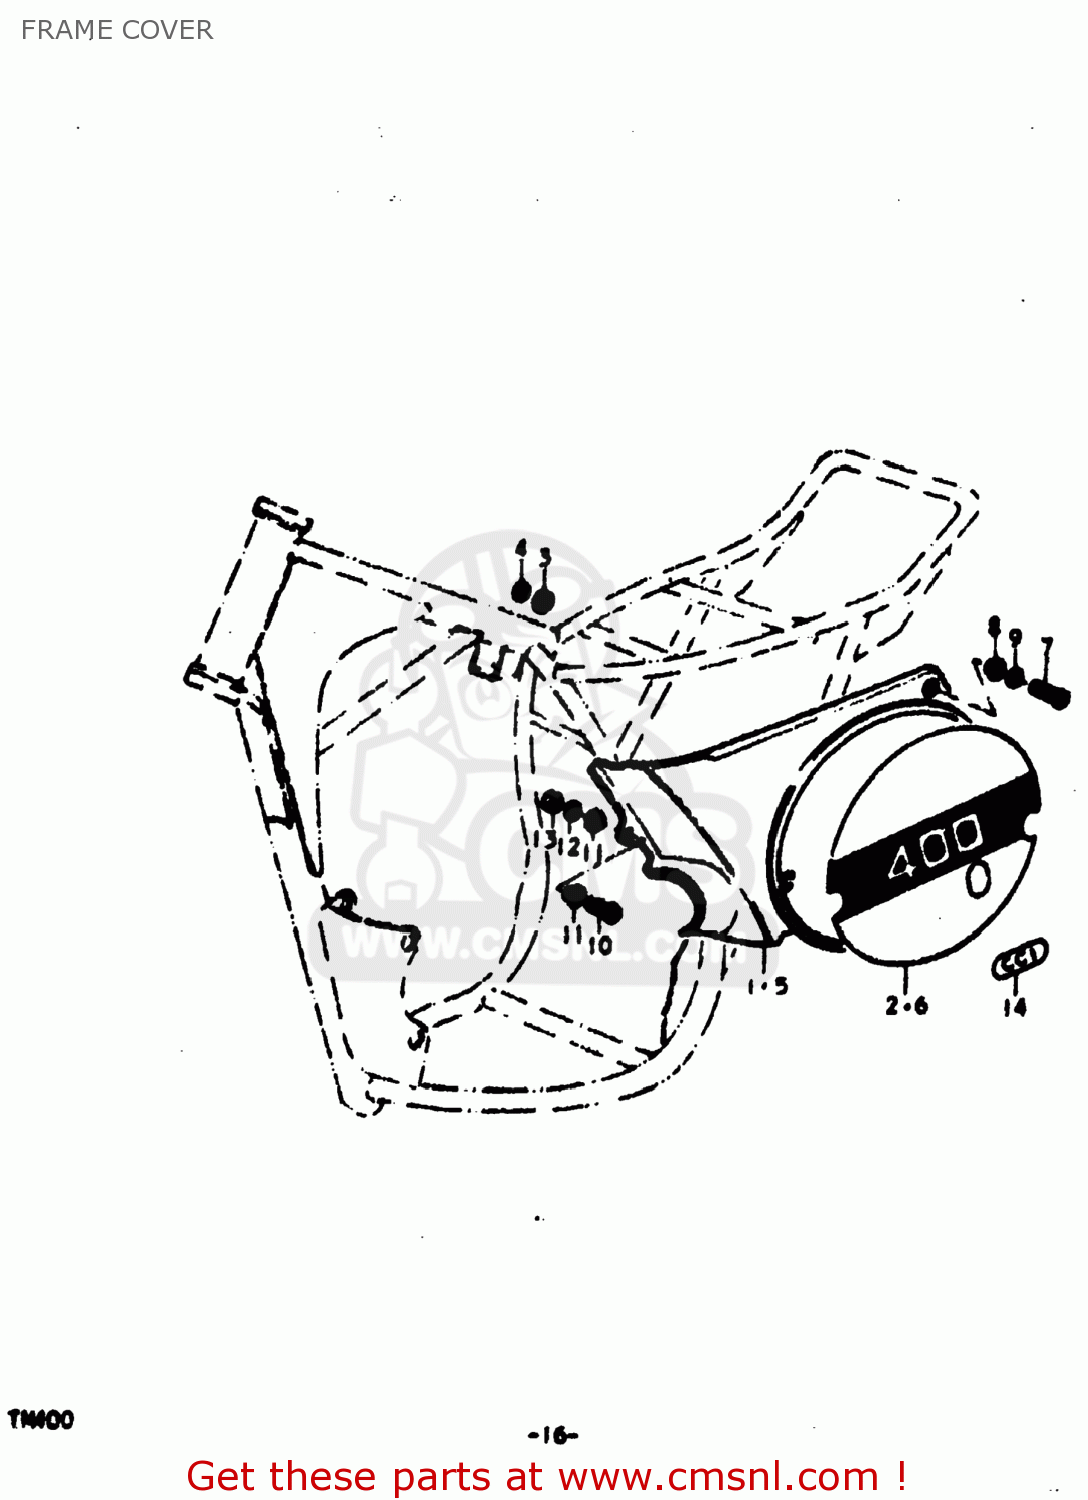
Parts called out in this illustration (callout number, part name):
1	COVER,FRAME,RIGHT
2	EMBLEM
3	WASHER
4	LOCK WASHER
5	COVER,FRAME,LEFT
6	EMBLEM,FRAME COVER
7	SCREW
8	WASHER
9	LOCK WASHER
10	SCREW
11	WASHER
12	LOCK WASHER
13	NUT
14	EMBLEM,CCIS
